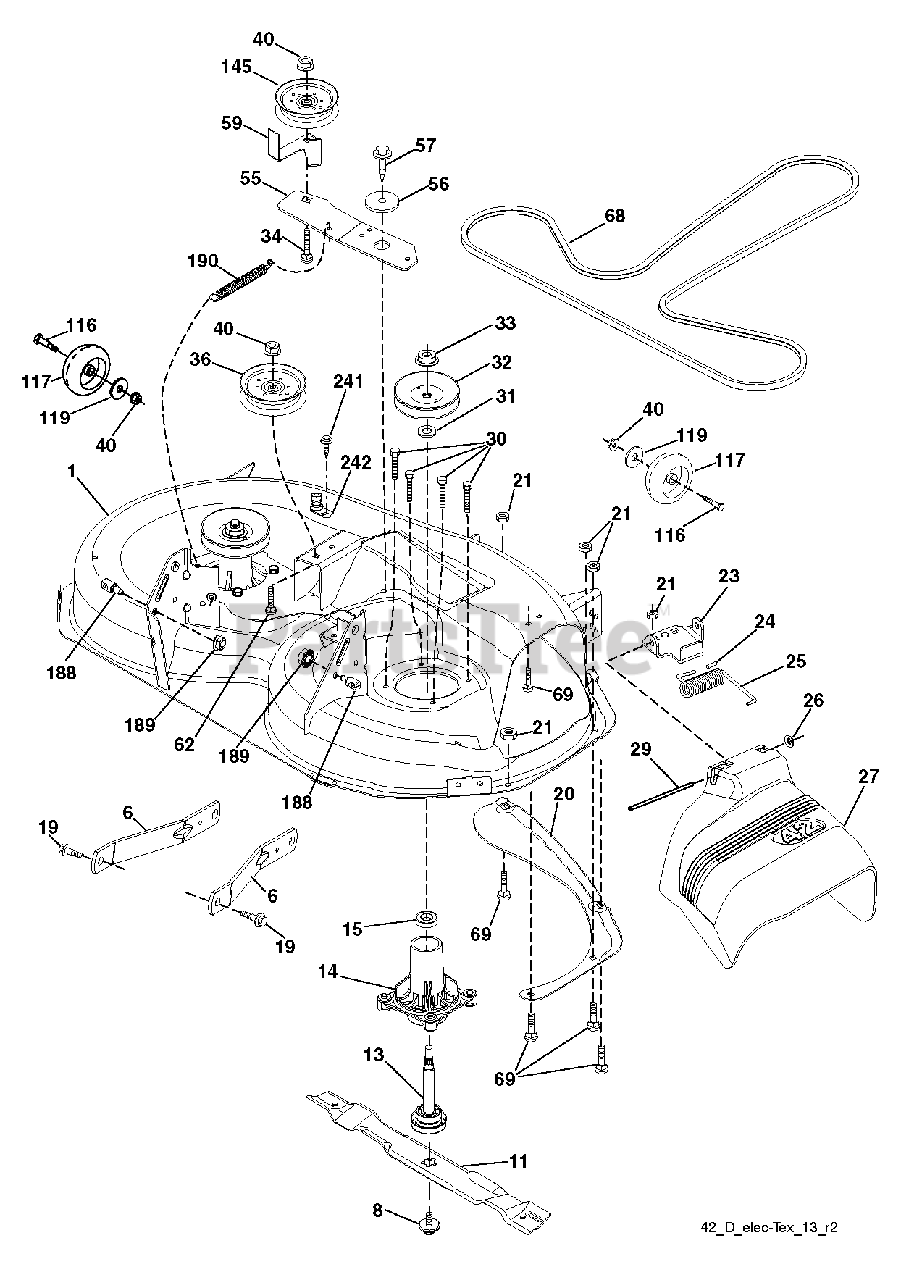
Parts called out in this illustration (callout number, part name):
6	ARM.SUSPENSION.MOWER.R
8	SCREW 7/16 X 20 X 1" HEX HEAD
11	BLADE.REVOLUTION 42"BAGGER
13	MANDREL.ASM.REV.TALL.N/GRSABLE
14	HOUSING.MANDREL.REV.TALL.N/GRS
19	BOLT.SHOULDER
20	BAFFLE.VORTEX
21	LOCKNUT
23	BRKT.DEFLECTOR.38"2005+
24	CAP-SLEEVE LT
25	SPRING.TORSION.DEFLECT
26	NUT PUSH M
27	SHIELD.DEFLECTOR.MOWER.42"BLAC
29	ROD.HINGE
30	SCREW, WASHER HEAD
31	WASHER.SPACER.MANDREL
32	PULLEY/MANDREL
33	NUT.FLANGE.LOCK.TOP
34	BOLT.3/8-16X1.50
36	PULLEY.IDLER.2006
40	NUT LOCK FLG 3/8-16 UNC
55	IDLER.ARM.42"
56	SPACER.RETAINER
57	SCREW 3/8-16X1
59	GUARD, BELT
68	BELT V SECONDARY
69	BOLT
116	BOLT M
117	WHEEL.GAGE.HALF.SPOKED
119	WASHER
145	PULLEY.IDLER.48"PRIMARY
188	STUD.FASTNER.W/ANTI-ROTATE
189	NUT LOCK HEX FLANGE 5/16-18
190	SPRING.MOWER.DRIVE.ELECTRIC
241	SCREW.TT.#10-32X.5.3/8.FLANGE
242	RP MANDREL.ASM.REV.TALL.N/GRS
